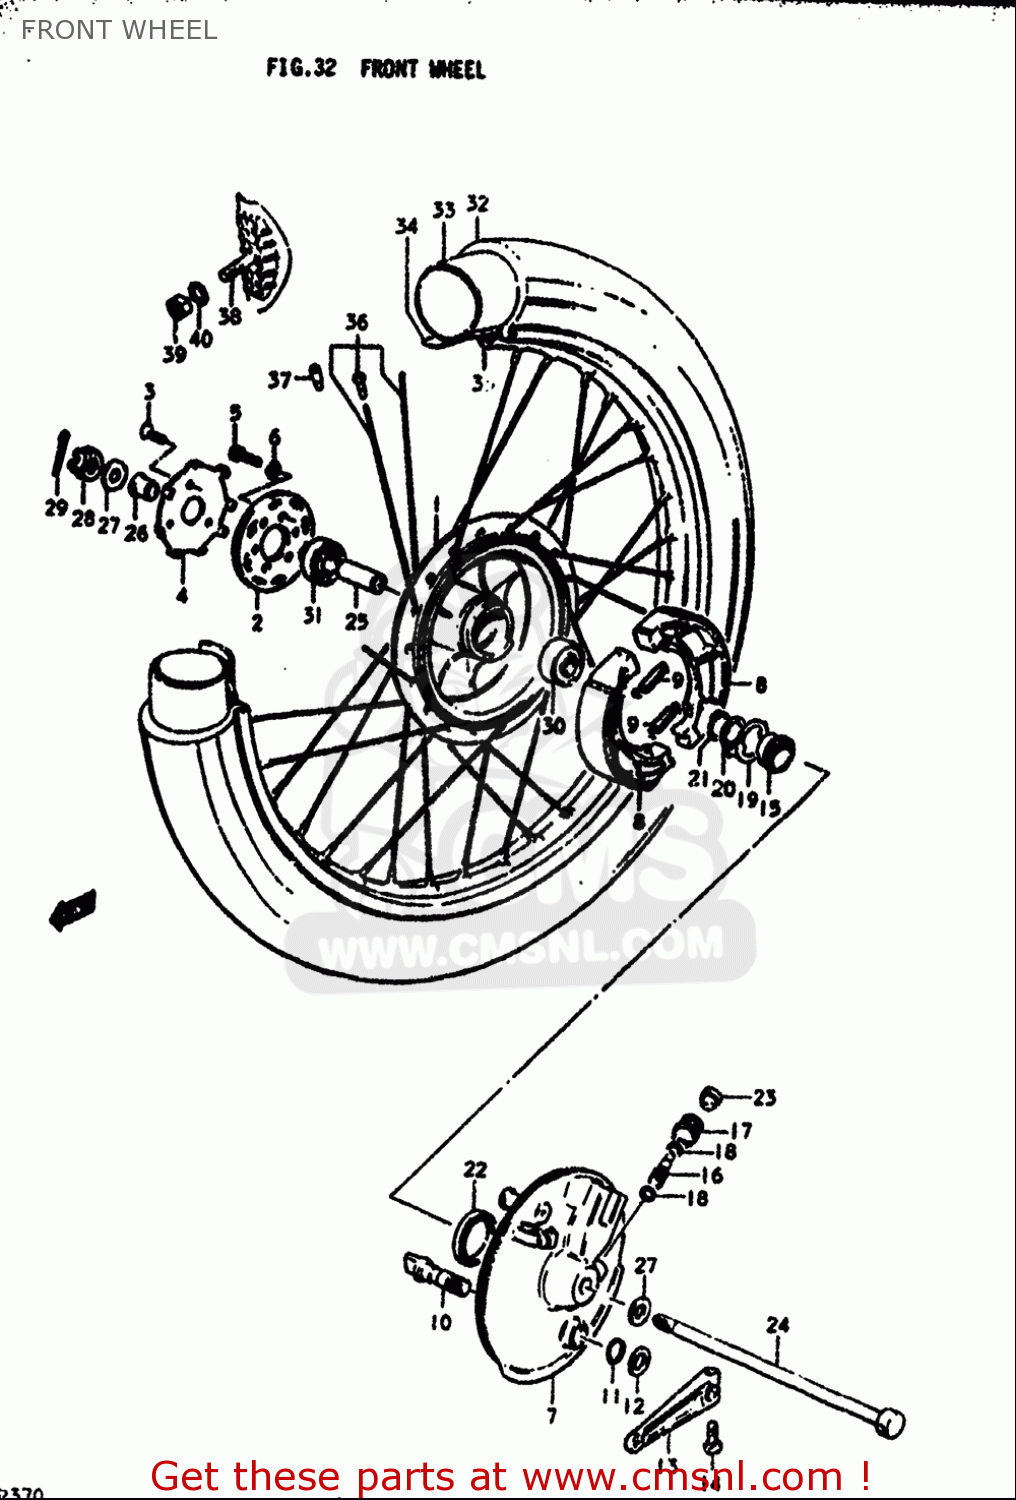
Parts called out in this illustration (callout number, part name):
2	FLANGE,FR HUB,R
3	SCREW
4	RETAINER,FR HUB BEARING,R
5	BOLT
6	WASHER,LOCK
8	SHOE SET,BRAKE (NAS)
9	SPRING
11	O RING(D:2.4,ID:14.8)
12	WASHER(15.5X24X1.6)
13	LEVER,FR BRAKE CAM
14	BOLT
17	BUSHING,SPEEDOMETER PINION
18	WASHER(5.1X9X0.4)
19	DRIVER,SPEEDOMETER GEAR
20	WASHER(22.5X27X1)
21	CIRCLIP
22	SEAL,OIL(26X38X4)
23	SEAL,OIL(6X10X3)
24	AXLE,RR
25	SPACER(12.5X19X52)
26	SPACER,FR AXLE,R
27	WASHER
28	NUT
29	PIN
30	BEARING
31	BEARING (12X32X10)
33	TUBE
34	PROTECTOR,WHEEL INNER
36	SPOKE SET,FR
37	BALANCER,WHEEL (50G)
38	STOPPER,BEAD
39	NUT
40	WASHER
